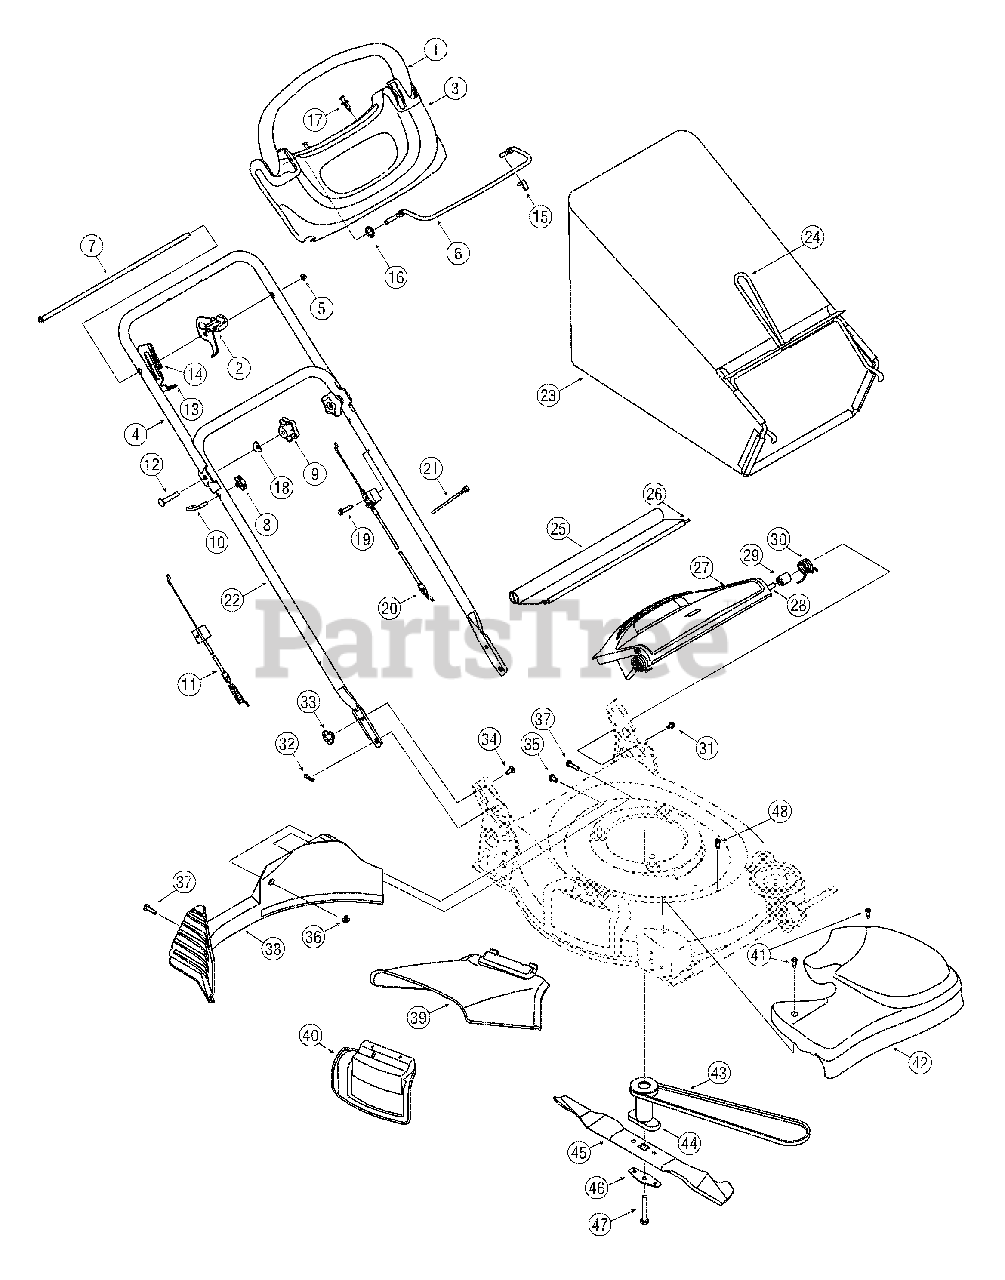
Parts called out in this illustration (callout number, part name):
1	Drive Control Bar: Red
2	Self Start Control Assembly
5	Speed Cap 1/4" Rod
6	Blade Control Bar
9	Handle Knob
11	Smart Speed™ Control Cable
12	Carriage Bolt 5/16-18 x 2.0
13	Cable Bracket
14	Extension Spring
15	Control Bar Stop Gray
17	Plastic Rivet
18	Saddle Washer
19	TT-Scr. 1/4-20 x 1.25
20	Smart Speed ™ SS Fwd. Drive Cable
21	Cable Tie
23	Grassbag Assembly
25	Rear Trailing Shield
26	Wire
27	Rear Discharge Door
29	Spacer.375 x.50 x 1.02
30	Torsion Spring LH
30	Torsion Spring RH
31	TT Screw 1/4-20 x 0.5
32	Cotter Pin
33	Wing Nut
34	Carriage Bolt 1/4-20
35	Machine Screw 1/4-20
36	Flange Lock Nut 1/4-20
37	HL Screw 1/4-15
38	Rear Baffle 21" Rd.
39	Chute Deflector
40	Mulch Plug Comp.
41	Shoulder Screw # 12 -24
42	Transmission Cover
44	Blade Adapter w/ Pulley
45	21" Mulching Blade
46	Blade Bell Support
47	Hex Screw 3/8-24 x 2.50
48	Shoulder Screw 1/4-14
